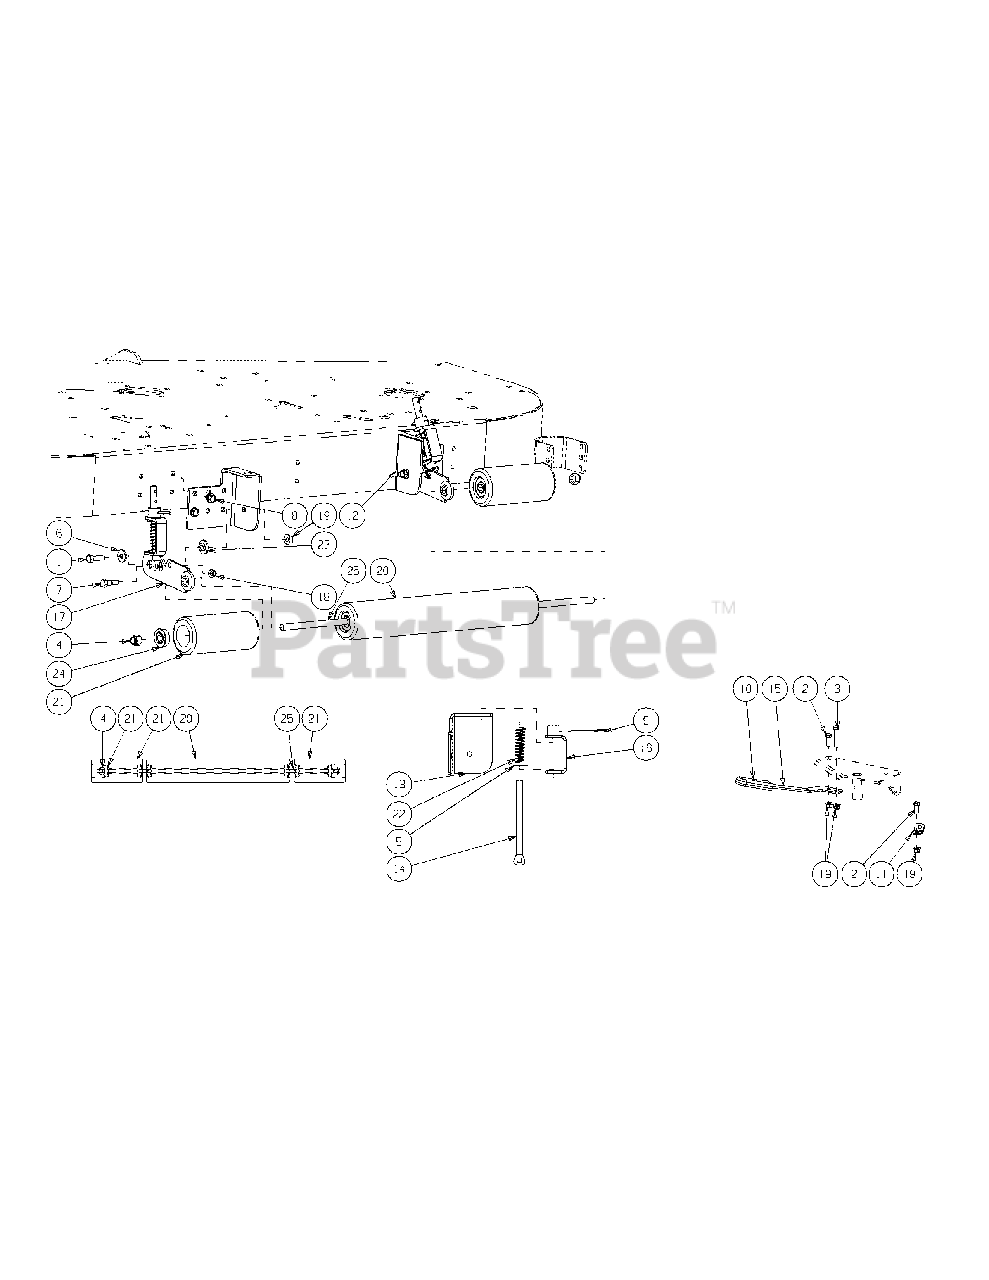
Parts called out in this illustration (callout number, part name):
1	HHCS, 3/8-16 x 1-1/4
2	HHCS, 3/8-16 x 1.00
3	HHCS, 3/8-16 x 2.00
4	Nut, 1/2-13, Nylon Insert
5	Washer, 1/2 Zinc
6	Flat Washer, .406 ID, 1.0 OD, .105
7	Shoulder Bolt
8	Hex Index Washer Screw, 3/8-16,.5
9	HitchPin, .120 Dia. x 3.0
11	Spring Mounting Bracket, 45 degree
12	Striper Mounting Bracket, LH
15	Idler Tension Handle
16	Striper Adjustment Clip Assembly
17	Striper Arm Bracket Assembly
18	Nylon Nut, 5/16-18, Flangelock
19	Nylon Nut, 3/8-16, Flangelock
20	Roller, 18.20" w/ Insert
21	Roller, 6.5" w/ Insert
22	Compression Spring, .72 OD x 2.75
23	Shoulder Spacer, .625 Dia. x .190
24	Roller Bearing, .5" ID
25	Striper Roller Rod
